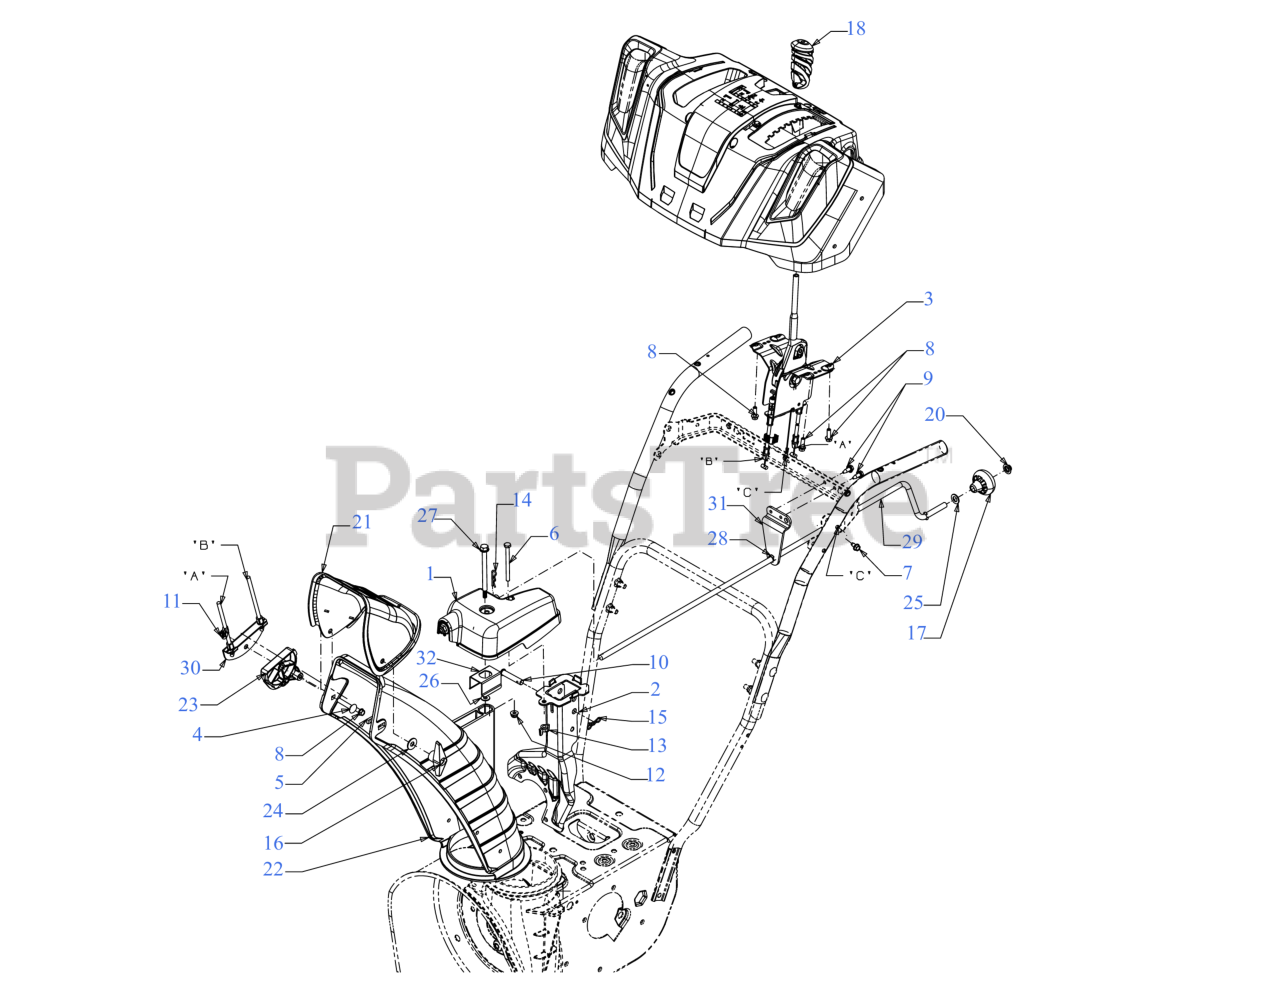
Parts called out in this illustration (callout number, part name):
1	GEARBOX ASSEMBLY
2	CHUTE SUPPORT BRACKET ASSEMBLY (POWDER BLACK)
3	CHUTE CONTROL
4	CARRIAGE BOLT 5/16-18 x 1.50
5	CARRIAGE BOLT 5/16-18 x 1
6	SCREW 1/4-20 x 3.0 GR5
7	SCREW 1/4-20 X.500
8	SCREW 1/4-15 x .750
9	SCREW 1/4-20X.625
10	CLEVIS PIN 3/8 x 1.87
11	FLANGE LOCK NUT 5/16-18
12	FLANGE LOCK NUT
13	WING NUT 1/4-20
14	INTERNAL COTTER PIN-1/2 DIA
15	BOW TIE COTTER PIN 1/4-5/16
16	WING NUT KNOB
17	SHIFT KNOB
18	PTO HANDLE GRIP .355 ID
20	PUSH NUT
21	UPPER REMOTE CHUTE WITH LABEL
22	LOWER CHUTE 5"
23	CABLE CHUTE GUIDE
24	FLAT WASHER
25	FLAT WASHER
26	FLAT WASHER
27	SHOULDER SCREW
28	BUSHING .380 ID
29	CHUTE CRANK (POWDER BLACK)
30	CABLE BRACKET
32	CHUTE BRACKET
